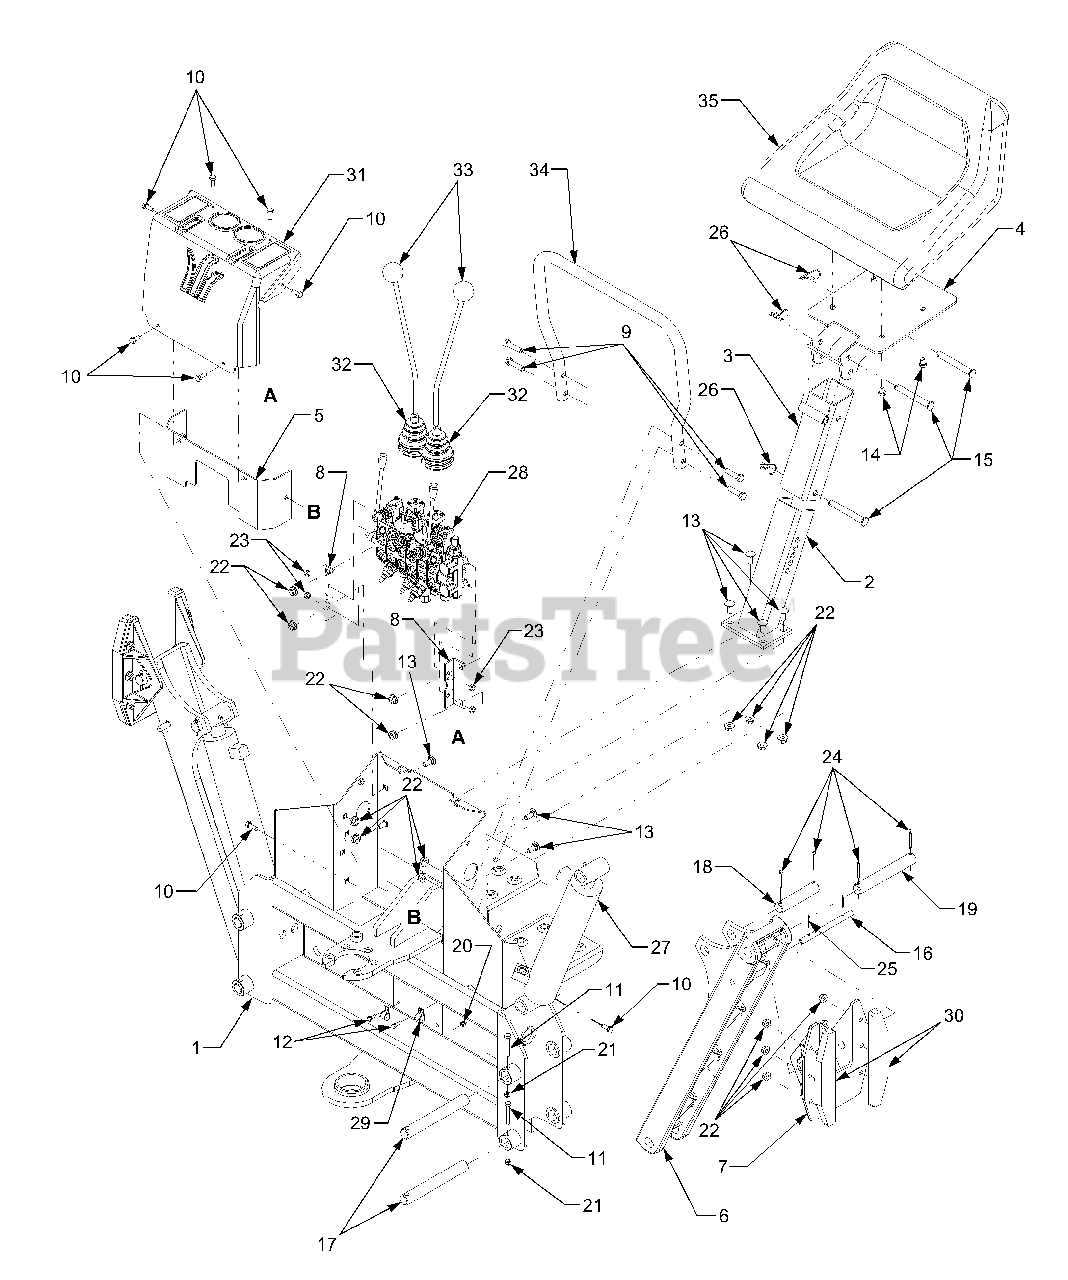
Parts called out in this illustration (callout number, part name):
1	Base Assembly
2	Mount Assembly, Seat
3	Pedestal, Seat
4	Hinge Plate, Seat
5	Bracket, Hose Guard
6	Arm, Stabilizer
7	Pad, Stabilizer
8	Bracket, Valve Mounting
9	Screw, Hex Cap, M10 -1.5 x 40 Gr10.9
10	Screw, Hex Cap, M8-1.25 x 20 Hardened
11	Screw, Hex Cap, M8-1.25 x 50 Hardened
12	Screw, Hex Cap, M6-1.0 x 16 Hardened
13	Screw, Carriage, M10-1.5 x 25
14	Screw, Hex Cap, 3/8-16 x .5 GR5
15	Pin, Seat Pivot
16	Pin, Stablizer Pad
17	Pin, Stabilizer Wrist
18	Pin, Stabilizer Pad Wrist
19	Pin, Stabilizer Pad Wrist
20	Nut, Hex Nylon Lock, M6-1.0
21	Nut, Hex Nylon Lock, M8-1.25
22	Nut, Hex Flange, M10-1.5
23	Nut, Hex, M8-1.25 GR 8.8
24	Pin, Cotter, 3/16 x 1.5
25	Pin, Cotter, 3/32 x 1.25
26	Pin, Internal Cotter
27	Cylinder, Stabilizer Arm
28	Valve, Hydraulic Control
29	Clamp, Hose, 9/16 Dia
30	Pad, Stabilizer
31	Cover, Valve
32	Boot, Valve Handle
33	Lever, Valve Control
34	Handle, Backhoe
35	Seat, Medium Back
